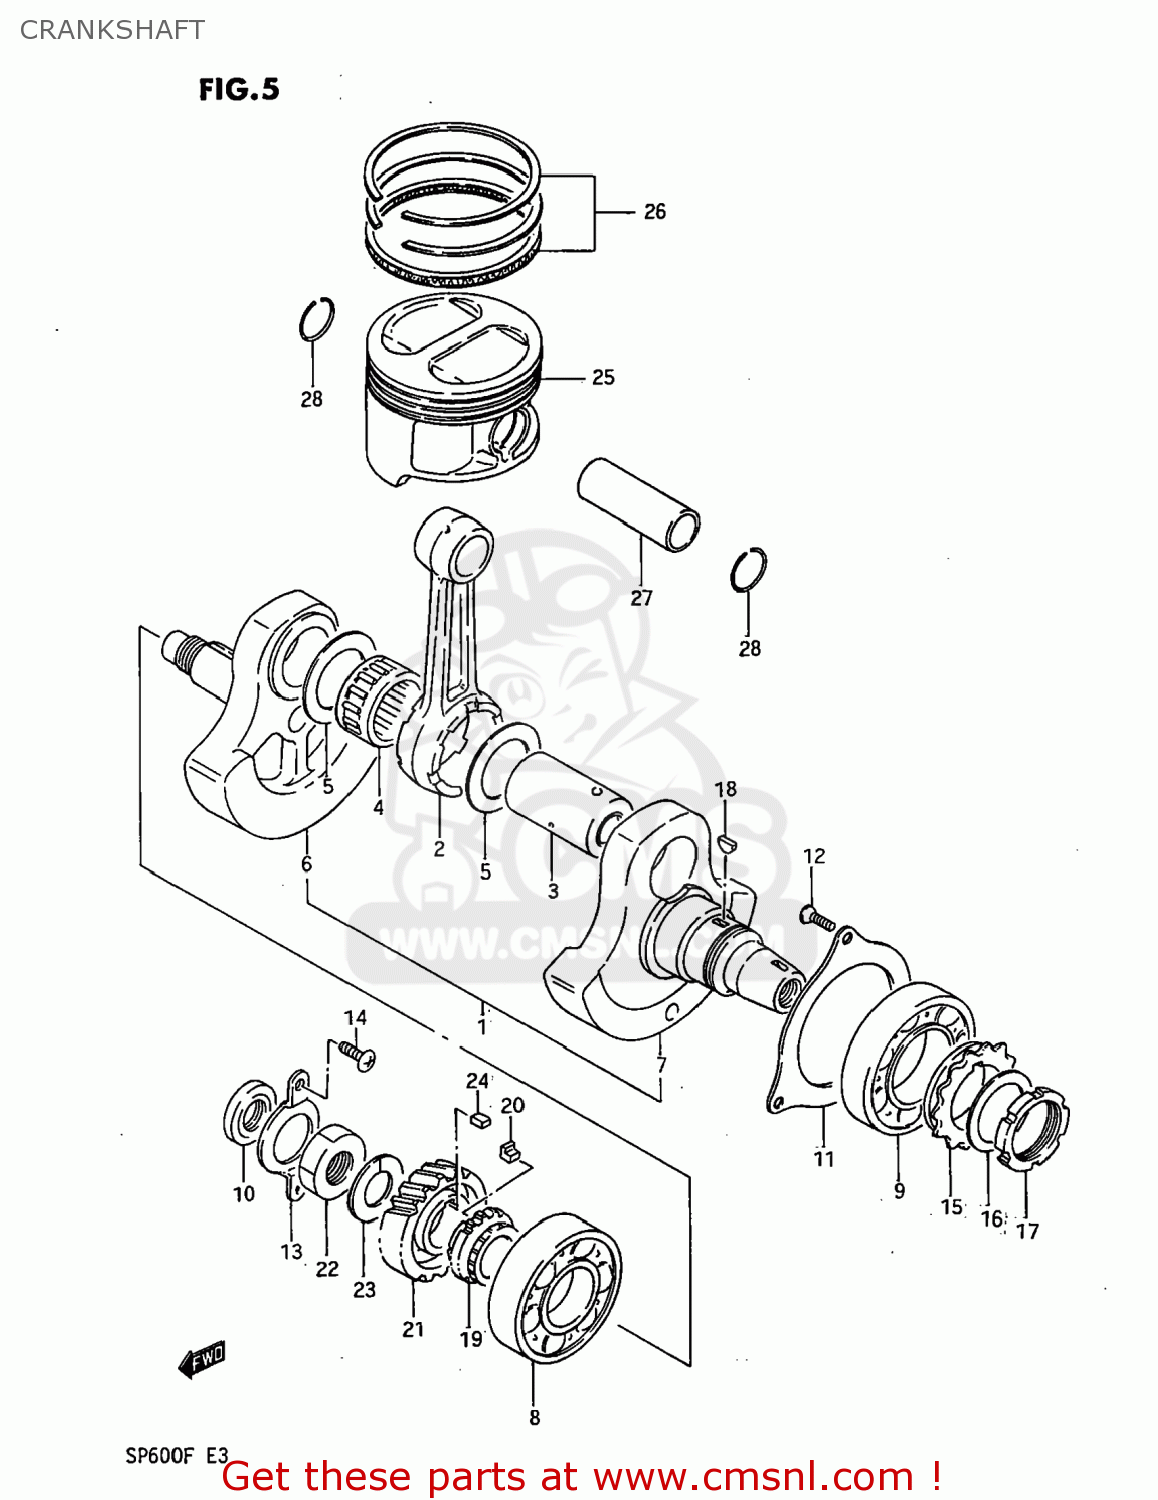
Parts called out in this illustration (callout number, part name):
1	CRANKSHAFT ASSEMBLY
2	CONNECTING ROD
3	PIN,CRANK
4	BEARING
5	WASHER(37X55X1)
6	CRANKSHAFT,RIGHT
7	CRANKSHAFT,LEFT
8	BEARING(35X80X21)
9	BEARING
10	SEAL,OIL(16X30X6)
11	RETAINER,CRANKSHAFT BEARING,L
12	SCREW
13	RETAINER,CRANKSHAFT BEARING,R
14	SCREW
15	SPROCKET,BALANCER DRIVE
16	WASHER
17	NUT,FLYWHEEL
18	KEY
19	SPROCKET,CAM CHAIN DRIVE
20	KEY,SPROCKET
21	GEAR,PRIMARY DRIVE
22	NUT (20MM)
23	WASHER
24	KEY
25	PISTON
26	RING SET,PISTON
27	PIN,PISTON
28	CIRCLIP
